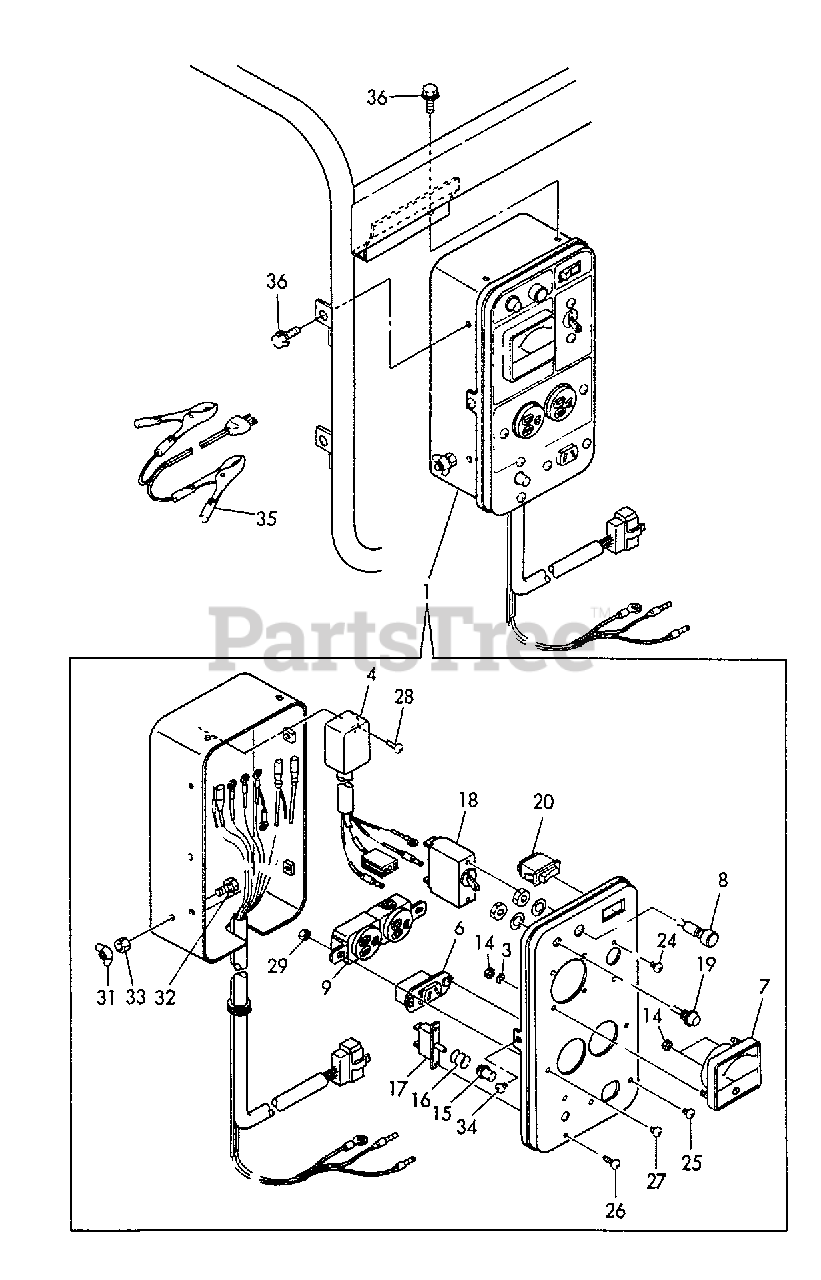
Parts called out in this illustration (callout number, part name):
1	PANEL BOX ASSY
3	LOCKWASHER
4	SENSOR, OIL
6	DC CONNECT
7	VOLT METER - 150V
8	LAMP, PILOT
9	AC CONNECT
14	NUT - 3
15	CAP, BREAKER
16	SPRING, BREAKER
17	BREAKER
18	AC BREAKER
19	LAMP, OIL ALERT
20	SWITCH
24	SCREW - 3X6
25	SCREW - 3X6
26	SCREW - 3X14
27	SCREW - 4X6
28	SCREW - 5X10
29	NUT - 4
31	WINGNUT - 6
32	BOLT - 6X16 -- PLATED
33	LOCKNUT - 6 -- PLATED
34	SCREW - 4X6
35	CABLE, CHARGING
36	BOLT - 6X8 -- PLATED
